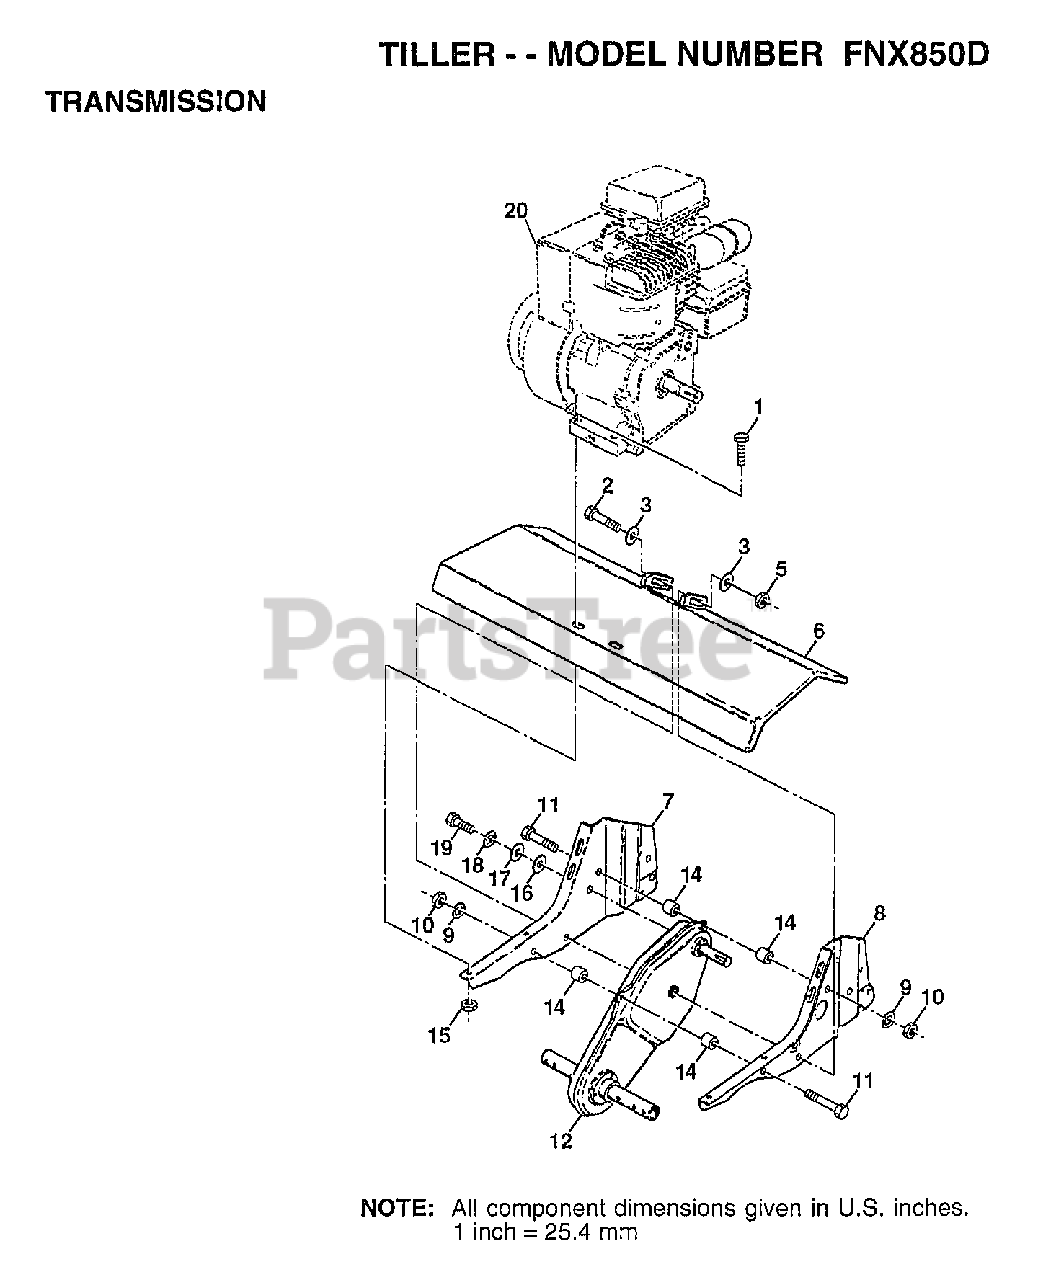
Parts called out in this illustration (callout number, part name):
1	BOLT.HEX.5/16-1.5
2	BOLT HEX 3/8-16
3	WASHER
5	NUT
6	TINE SHIELD
7	BRACKET.ENGINE.RH
8	BRKT.ENGINE.LH
9	LOCKWASHER
10	NUT.HEX.5/16-18
13	SPLIT SPACER RT
16	WASHER
17	WASHER
18	LOCKWASHER
19	BOLT
